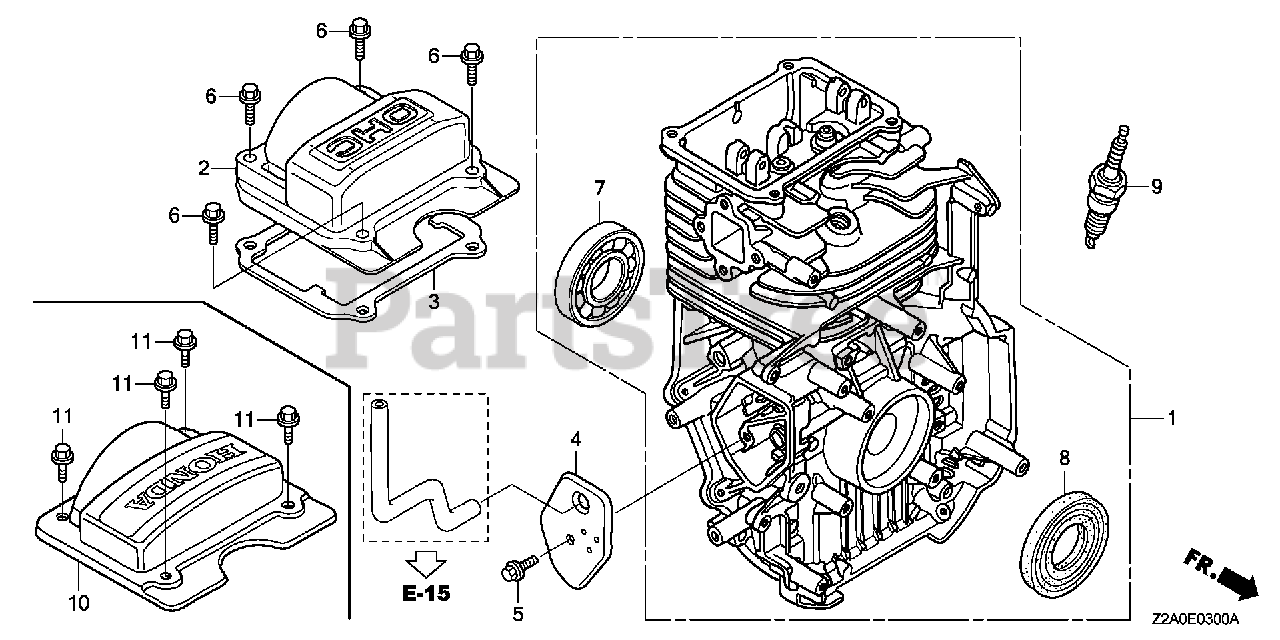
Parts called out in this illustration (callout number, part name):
1	CYLINDER ASSY.
4	COVER, BREATHER (BREATHER VALVE ASSY.)
5	BOLT, FLANGE (6X14) (CT200)
7	BEARING, RADIAL BALL
8	OIL SEAL (25.4X74X6)
9	SPARK PLUG (BPR6ES) (NGK)
10	COVER, CYLINDER HEAD
11	BOLT, FLANGE (6X12) (CT200)
